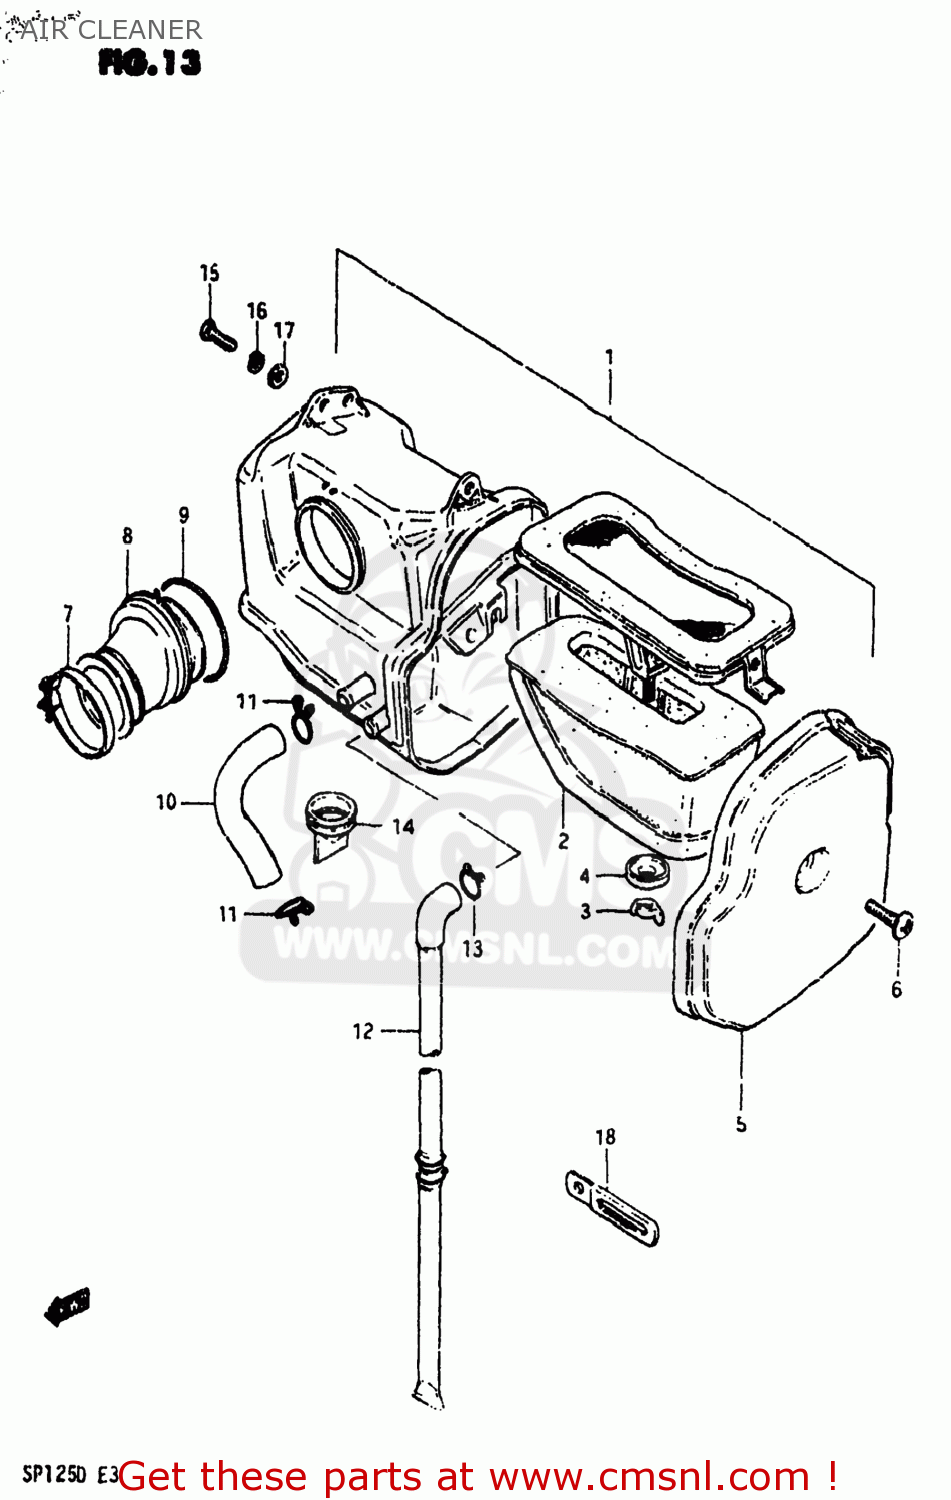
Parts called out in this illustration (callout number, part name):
1	CLEANER ASSEMBLY,AIR
2	ELEMENT,AIR CLEANER
3	NUT
4	WASHER
5	CAP
6	SCREW
7	CLAMP
8	TUBE,OUTLET
9	CLAMP,CLEANER SIDE
10	TUBE,AIR CLEANER BREATER
11	CLAMP
12	HOSE,AIR CLEANER DRAIN
13	CLAMP
14	DRAIN TUBE
15	BOLT, UPPER
16	LOCK WASHER
17	WASHER
18	CLAMP
